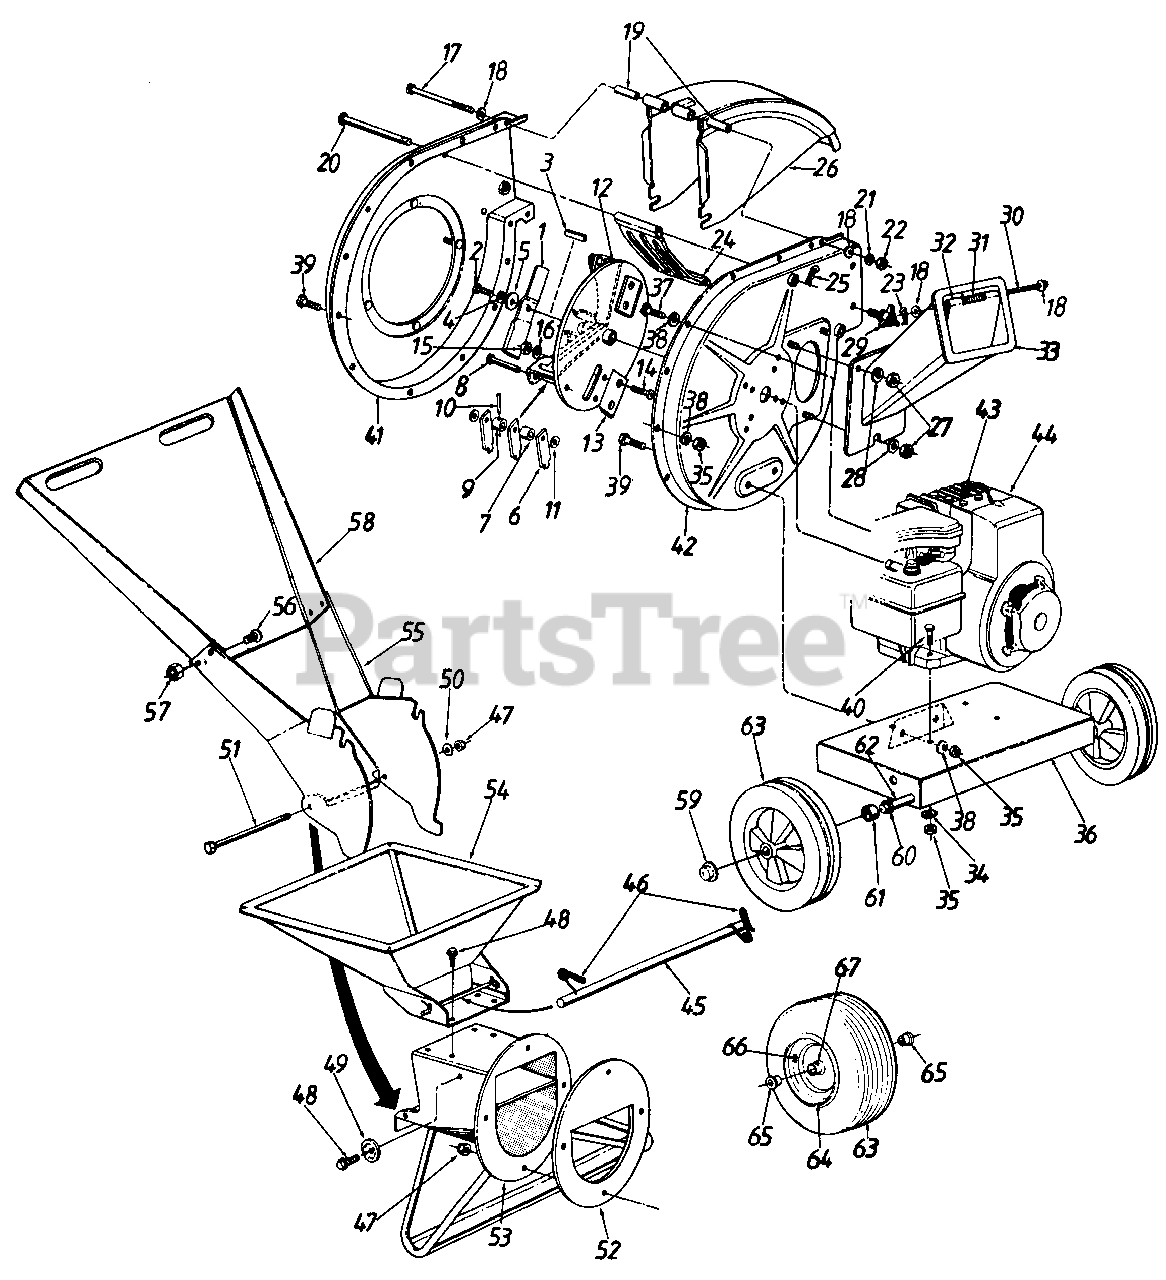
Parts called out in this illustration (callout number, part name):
3	KEY-SQ 1/4 X 2.00
4	WASHER-HDL 3/8
5	WASHER-FL-HOND .410ID X 1.255X.162
6	FLAIL
7	SPACER-FLAIL
8	PIN-CLEVIS
9	SPACER
10	PIN-SPRING ROLL 5/32 X 1.12
11	WASHER-FL-.531 ID X .93 OD X .090
12	HUB CAP
13	BLADE-CHIPPER
14	SCREW-FLAT HD
15	NUT-HEX INS L
16	WASHER-LOCK-5/16
17	BOLT-HEX 1/4-20 X 4 LG
18	WASHER-FL-.344 ID X .88 OD X .063
19	SPACER-.260 X .373 X 1.66
20	PIN-CLEVIS
21	LOCK WASHER 1/4 DIA
22	NUT-HEX 1/4-20
25	PIN-INTERN COT
27	NUT-HEX 5/16-18
28	WASHER-BELL .337 X .867 X .057
29	KNOB-THREE ARM
30	ROD-CHIPPER DOOR
31	SPRING-TORSION
35	NUT-HEX 5/16-18
36	FRAME-ENGINE MTG
37	SCREW-HEX 5/16-24 X .75
38	WASHER-LOCK-5/16
39	SCREW-HEX 5/16 X 3/4
40	SCREW-HEX 5/16-18 X 1.75
43	INSULATOR-SPARK PLUG
45	BAR-RELEASE
46	SPRING-TORSION
47	NUT-HEX INS L-5/16-18
48	SCREW-HEX WASH SF TAPP
49	WASHER-STOP
50	WASHER-FL-.344 X .62
51	SCREW-HEX 5/16-18 X 8.25
52	PLATE-BACK-UP
53	GUIDE ASSY-INLET
57	NUT-HEX CENTER L-1/4-20
60	WASHER-FL-.640ID X 1.24OD X .06HDN
61	SPACER
62	AXLE-SHREDDER 3&5 HP
63	WHEEL ASSY W/TIRE 645
64	WHEEL RIM
65	BEARING-FLANGE
66	VALVE-TUBELESS AIR
67	FITTING-GREASE (SLOTTED)
